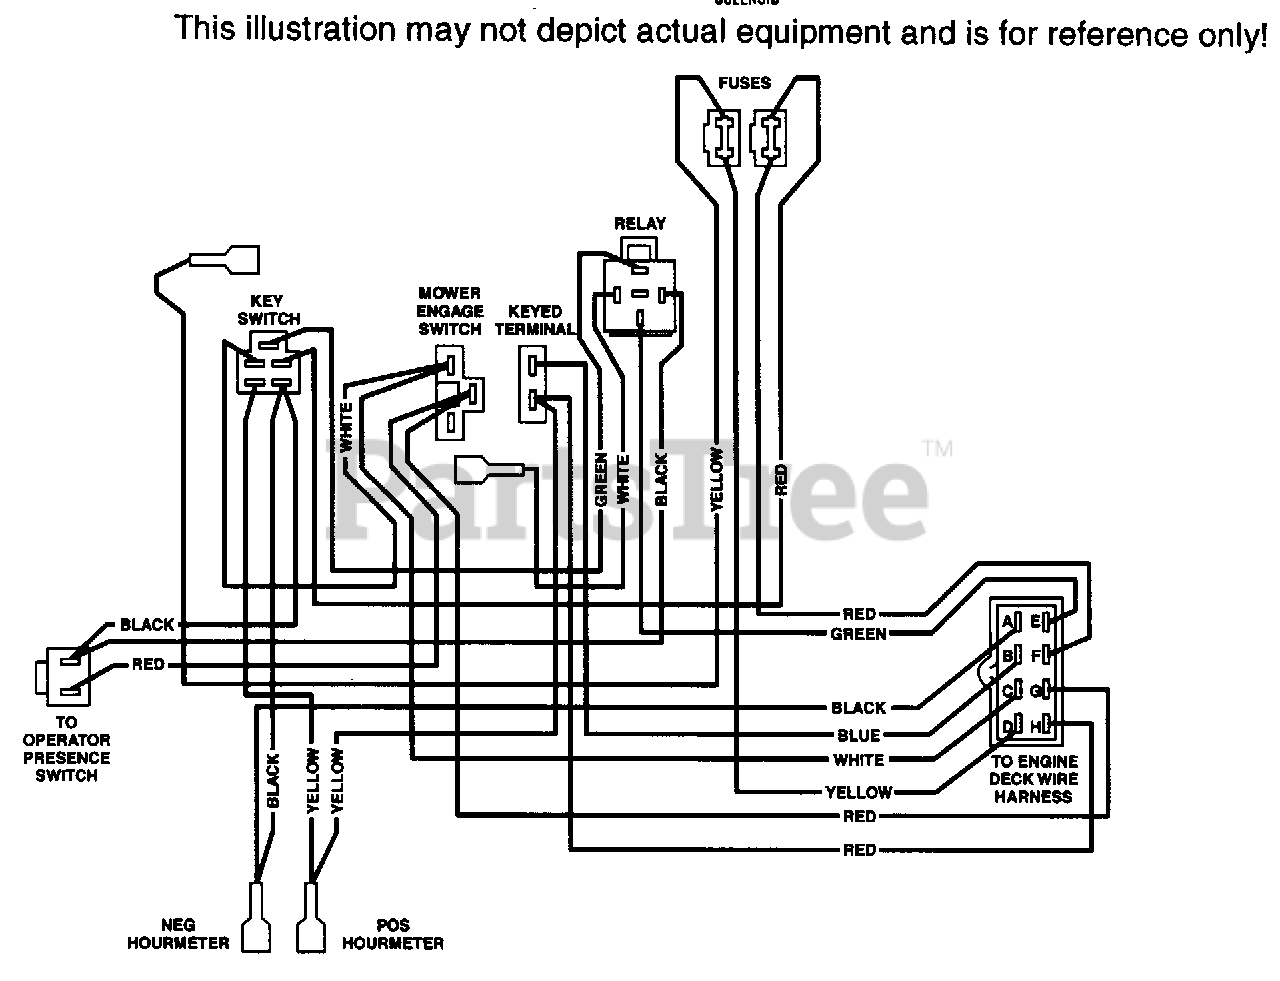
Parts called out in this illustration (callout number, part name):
1	ENGINE 20CVE KOHLER COMMAND
12A	FUEL HOSE, 1/4 ID X 23"
69	CHOKE CONTROL
81	PIPE, 4.75" NIPPLE
92A	BATTERY CABLE, 31.5 BLACK
